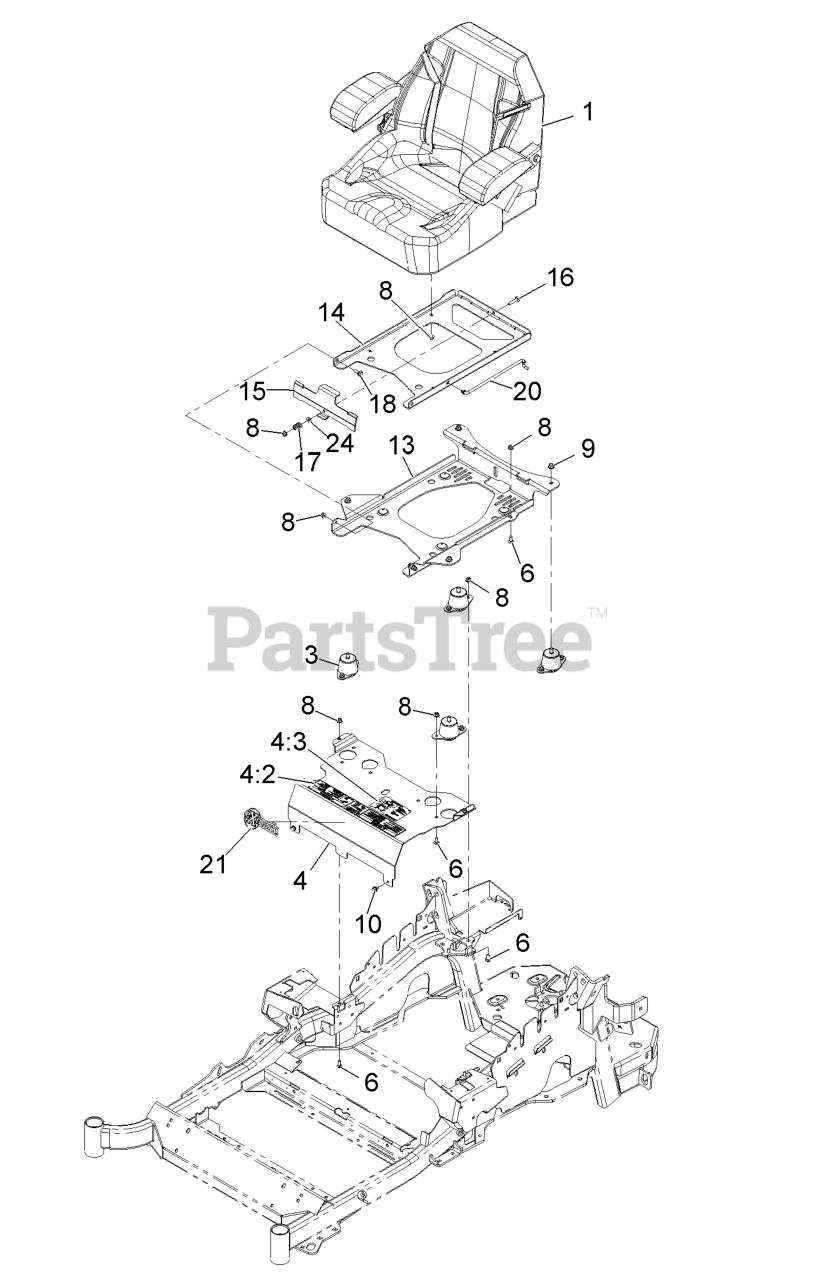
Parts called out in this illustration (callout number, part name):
3	ISOLATOR-SEAT
4	MOUNT-SEAT
4:2	DECAL-CONSOLE
4:3	DECAL-SERVICE AID
6	SCREW-CARR
8	NUT-HF, NI
9	NUT-HF, NI
13	PLATE-SUPPORT, SEAT TILT
14	PLATE-FRAME, SEAT TILT
15	PLATE-LATCH, SEAT
16	BOLT-CARR
17	SPRING-COMPRESSION
18	SCREW-SHOULDER
20	ROD-PROP
24	WASHER-PLAIN
